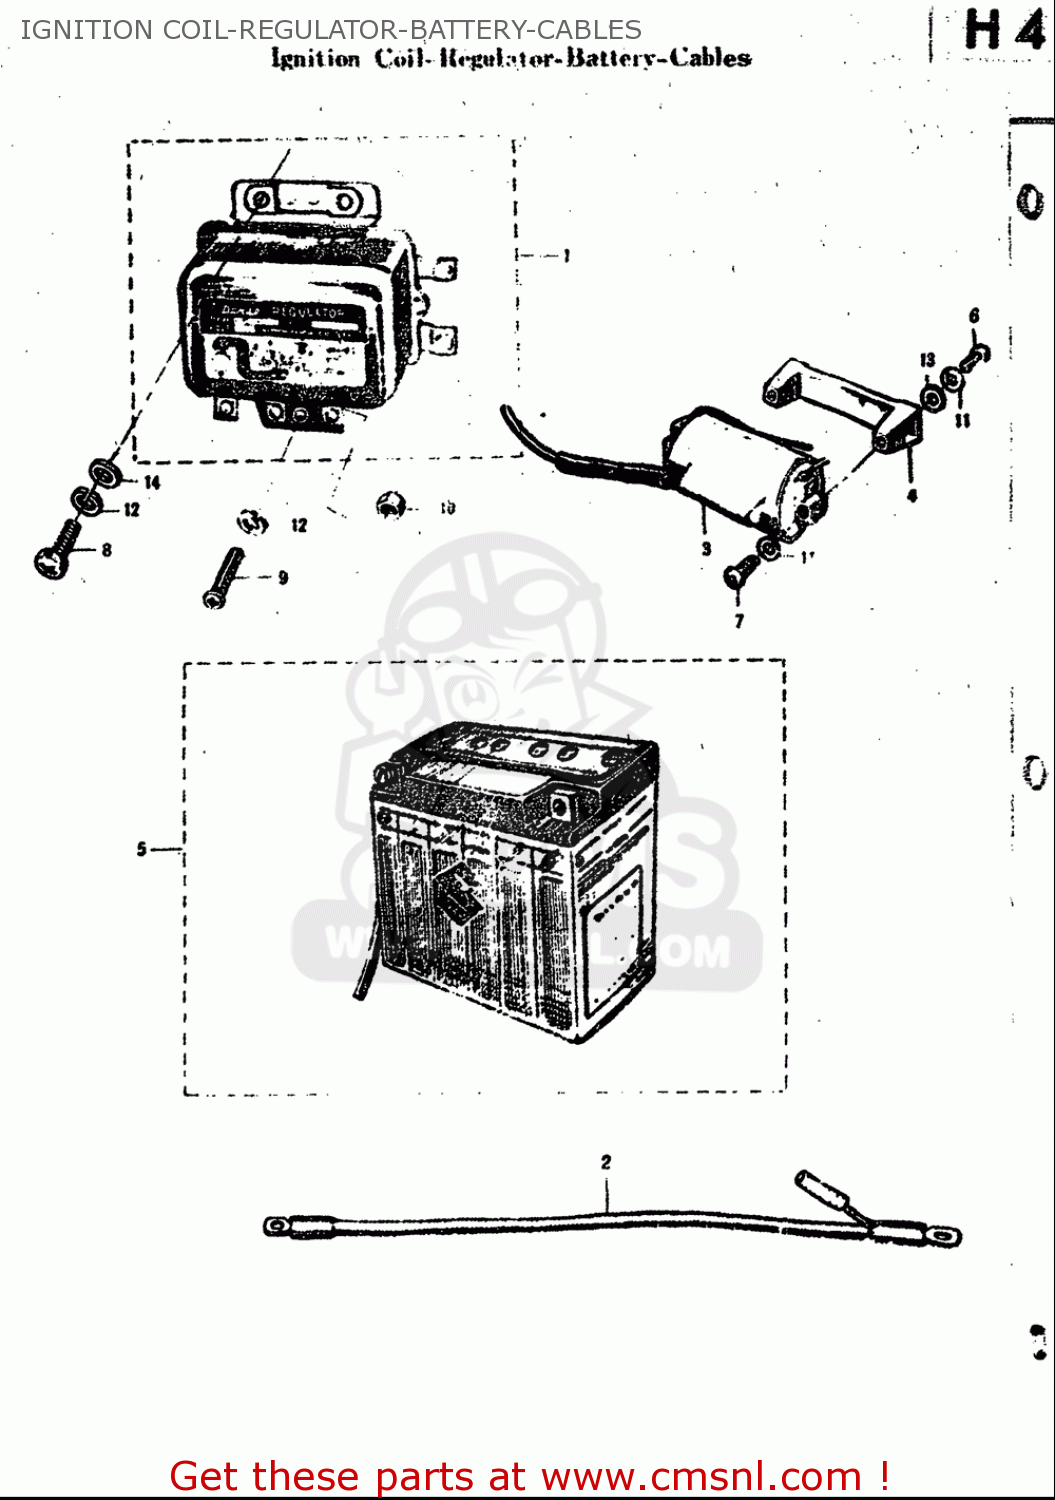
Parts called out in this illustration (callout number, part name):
10	NUT
11	WASHER,LOCK
12	WASHER,LOCK
13	WASHER
